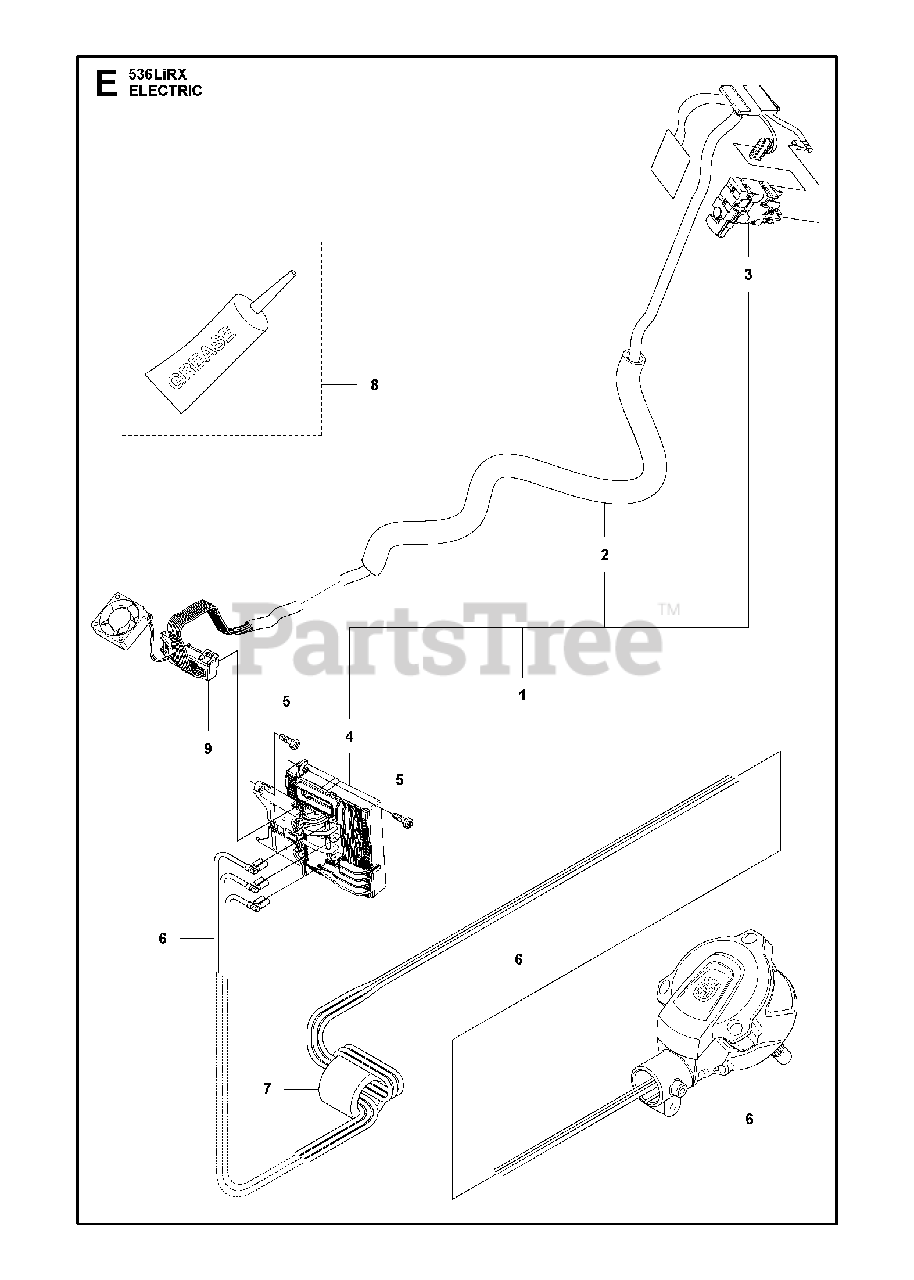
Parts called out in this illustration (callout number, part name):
3	TRIGGER SWITCH
4	CONTROL UNIT
6	MOTOR ASSY BLDC BLADE
7	FERRITE CORE
8	GREASE TUBE Q8 RUYSDAEL WR2
